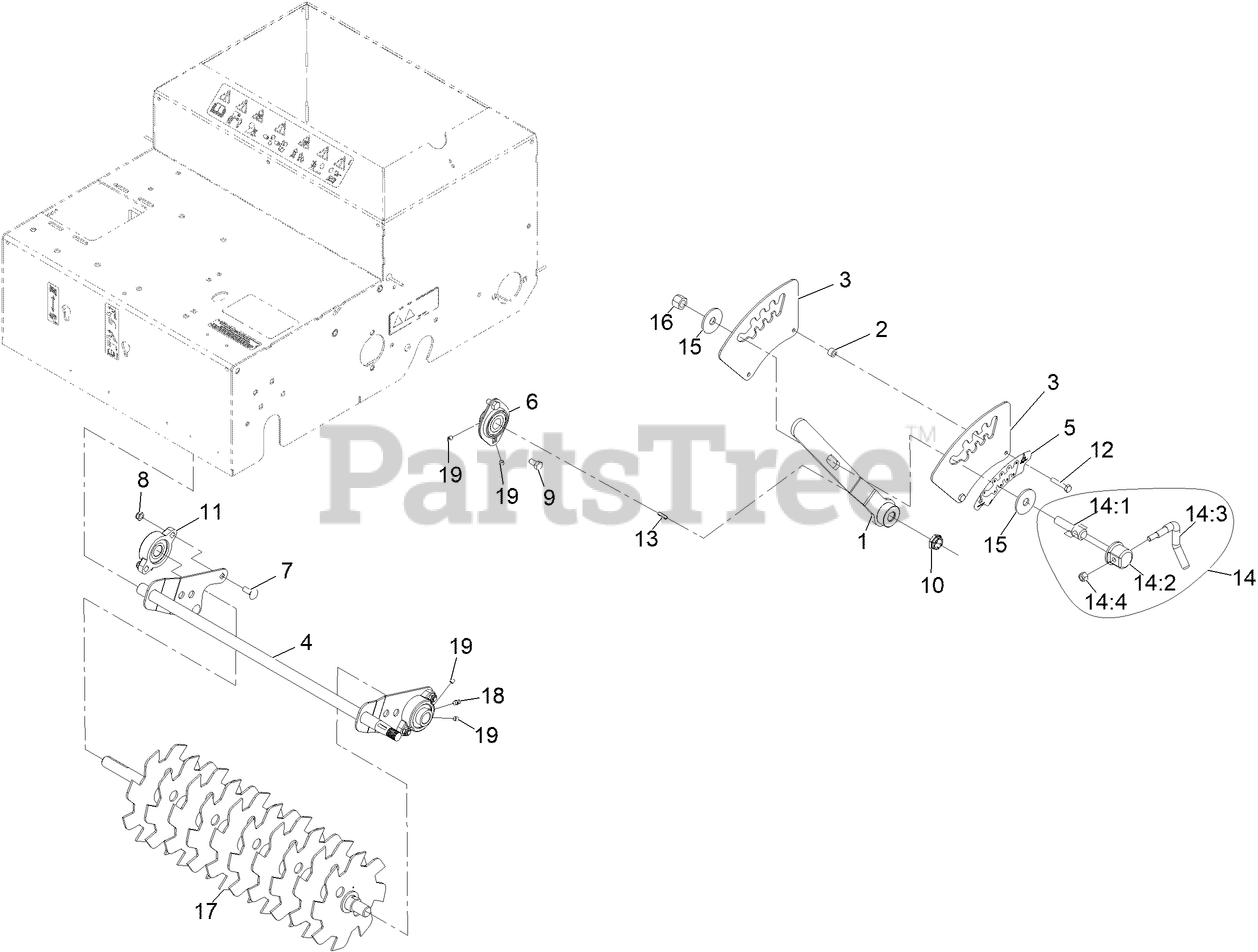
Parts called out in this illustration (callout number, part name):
1	HANDLE-HEIGHT
3	PLATE-HEIGHT
4	PIVOT-HEIGHT
5	DECAL-CUT DEPTH, SLICER/S
6	BEARING
7	SCREW-CARR
8	NUT-LOCK, NI
9	SCREW-HH
10	NUT-HEX, FLEXTOP
11	BEARING-FLANGE
12	Screw-HH
13	KEY-WOODRUFF
14	LEVER ASM
14:1	SCREW-LOCK
14:2	CAP-LOCK
14:4	NUT-LOCK, NI
15	WASHER-THRUST
16	NUT-LOCK, NI
17	SLICER SHAFT ASM
18	FITTING-GREASE
19	SCREW-SET, HSH
